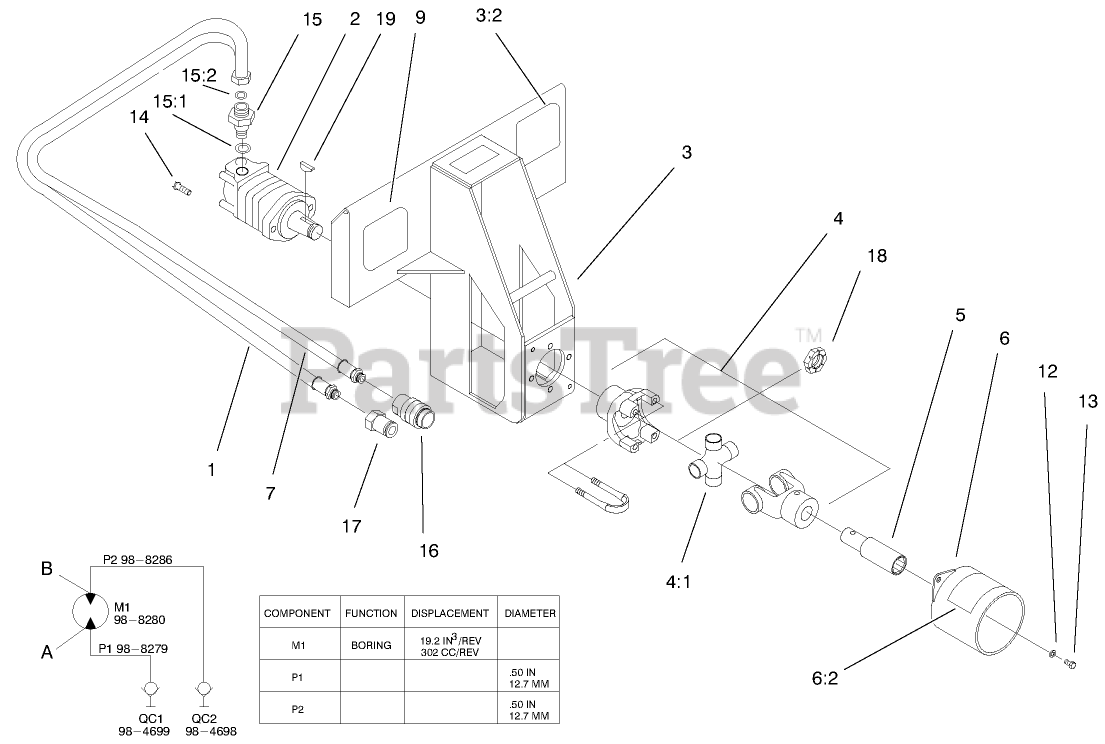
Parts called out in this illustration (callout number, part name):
1	HOSE - HYDRAULIC
2	MOTOR-HYDRAULIC
3	FRAME ASM
3:2	DECAL-WARNING
4	JOINT - UNIVERSAL
4:1	U-JOINT
5	COUPLER - SPLINE
6	SHIELD ASM
6:2	DECAL-WARNING
7	HOSE - HYDRAULIC
9	DECAL - SIDE
12	SCREW-HH
13	WASHER-LOCK
14	SCREW
15	FITTING-STRAIGHT
15:1	O-RING
15:2	O-RING
16	FEMALE-DISCONNECT, QUICK
17	MALE-DISCONNECT, QUICK
18	Nut-Shaft
19	KEY - SHAFT
